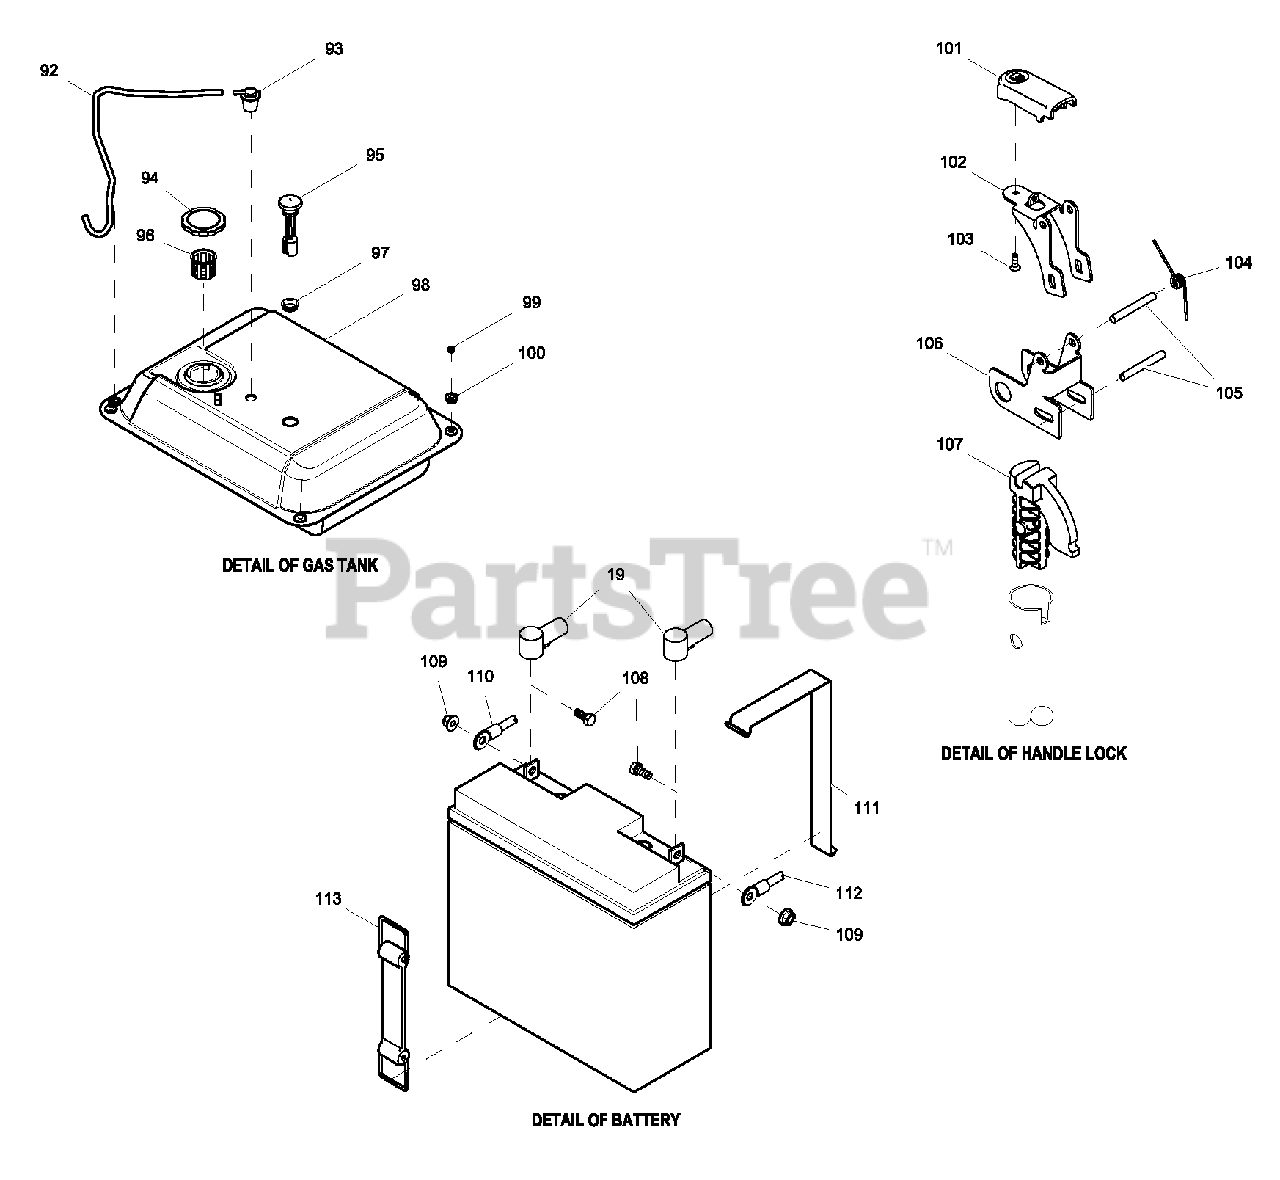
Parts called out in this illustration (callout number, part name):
92	FUEL HOSE 365MM LONG
93	ASSY, ROLL OVER SLANT VALVE
94	ASSY GAS CAP SEALED - BLACK
95	FUEL GAGE ROUND MULTI TWIST
96	FILTER, FUEL
97	GROMMET FUEL GAUGE ROUND
98	WELDMENT FUEL TNK 9 GAL XP RAW
99	INSERT, ANTI-CRUSH FOR TANKS
100	RUBBER MOUNT, 10.8 ID X 9 TALL
101	BUTTON LATCH RELEASE
102	LEVER, LATCH RELEASE
103	SCREW PFHP #8-16 X 1/2
104	SPRING TORSION, LATCH RELEASE
105	PIVOT PIN, LATCH RELEASE
106	BRACKET, LATCH
107	PLUG, FOLD DOWN HANDLE
108	SCREW HHC M5-0.8 X 10 C8.8
109	NUT HEX FL WHIZ M5-0.8
110	WIRE ASSY,BATT NEG/ENG BLK,XP
111	BRKT BTTRY TRAY XP10 RAW
112	WIRE ASSY,BATT POS/STARTER,XG
113	ASSEMBLY, BATTERY STRAP
